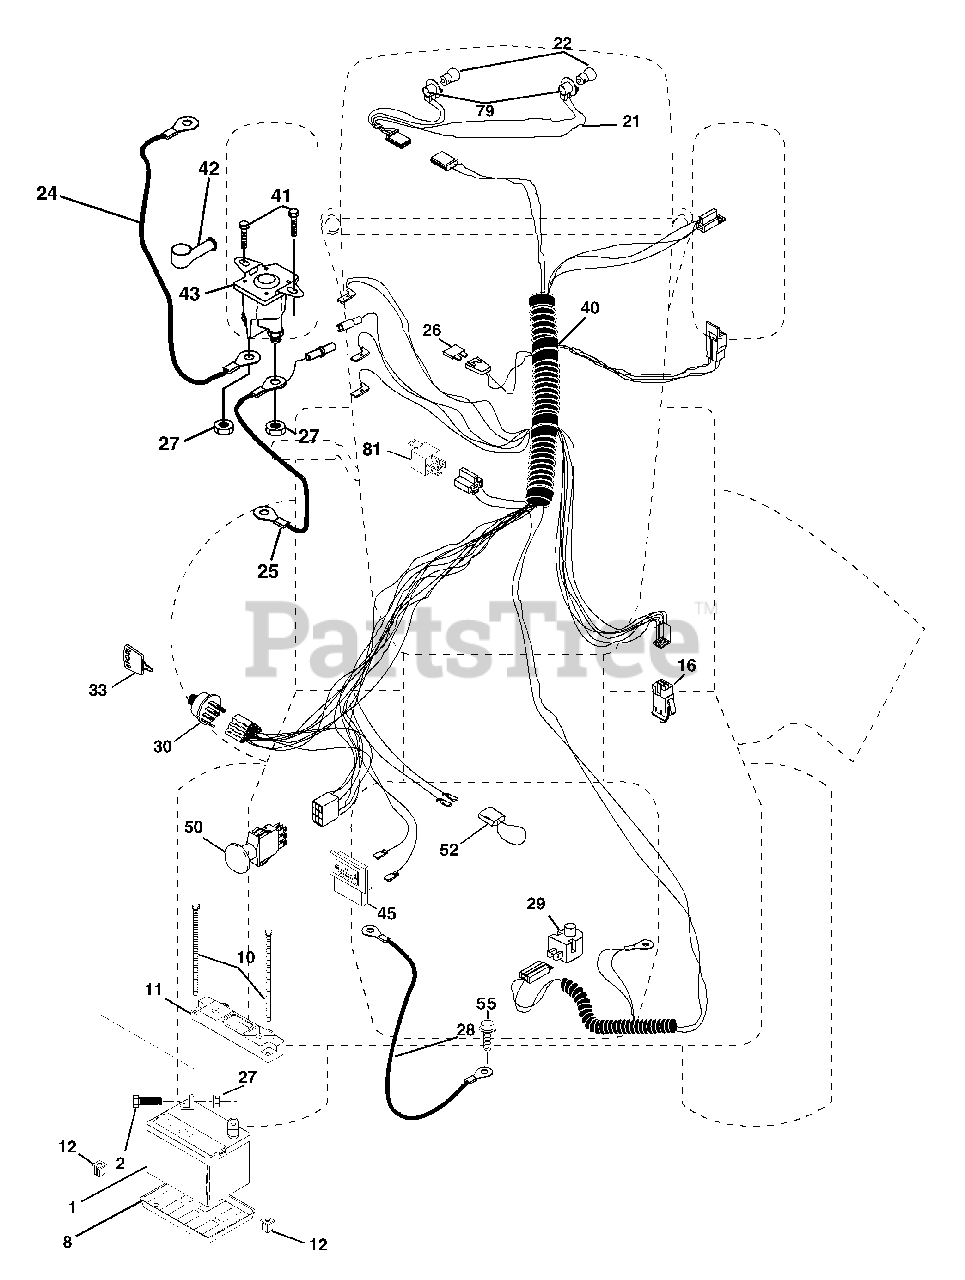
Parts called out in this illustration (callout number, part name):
1	Battery
2	Bolt Hex Hd 1/4-20 UNC X 3/4
8	Tray, Battery
10	Bolt, BTR FRT 1/4-20 x 7.5
11	Hold Down Battery, Front
12	Nut, Push, Nylon
16	Switch Interlock Push-In
21	Harness Asm Light W/4152j
22	Bulb Light
24	Cable Battery
25	Cable Batterywire
26	Fuse
27	Nut Keps Hex 1/4-20 Unc
28	Cable Ground
29	Switch Plunger Normal OP Olive
30	Switch Ign 4 pos w/lights
33	Key Ign
40	Harness Ign.
41	Bolt Blk Fin Hex 1/4-20 x 1/2
42	Cover Terminal Red
43	Solenoid
45	Ammeter Rectangular
50	Switch, PTO
52	Protection wire Loop (Hour Meter)
55	Screw Thdrol 5/16-18 x 1/2
79	Socket Asm Bulb Twistlock
81	Relay Asm
